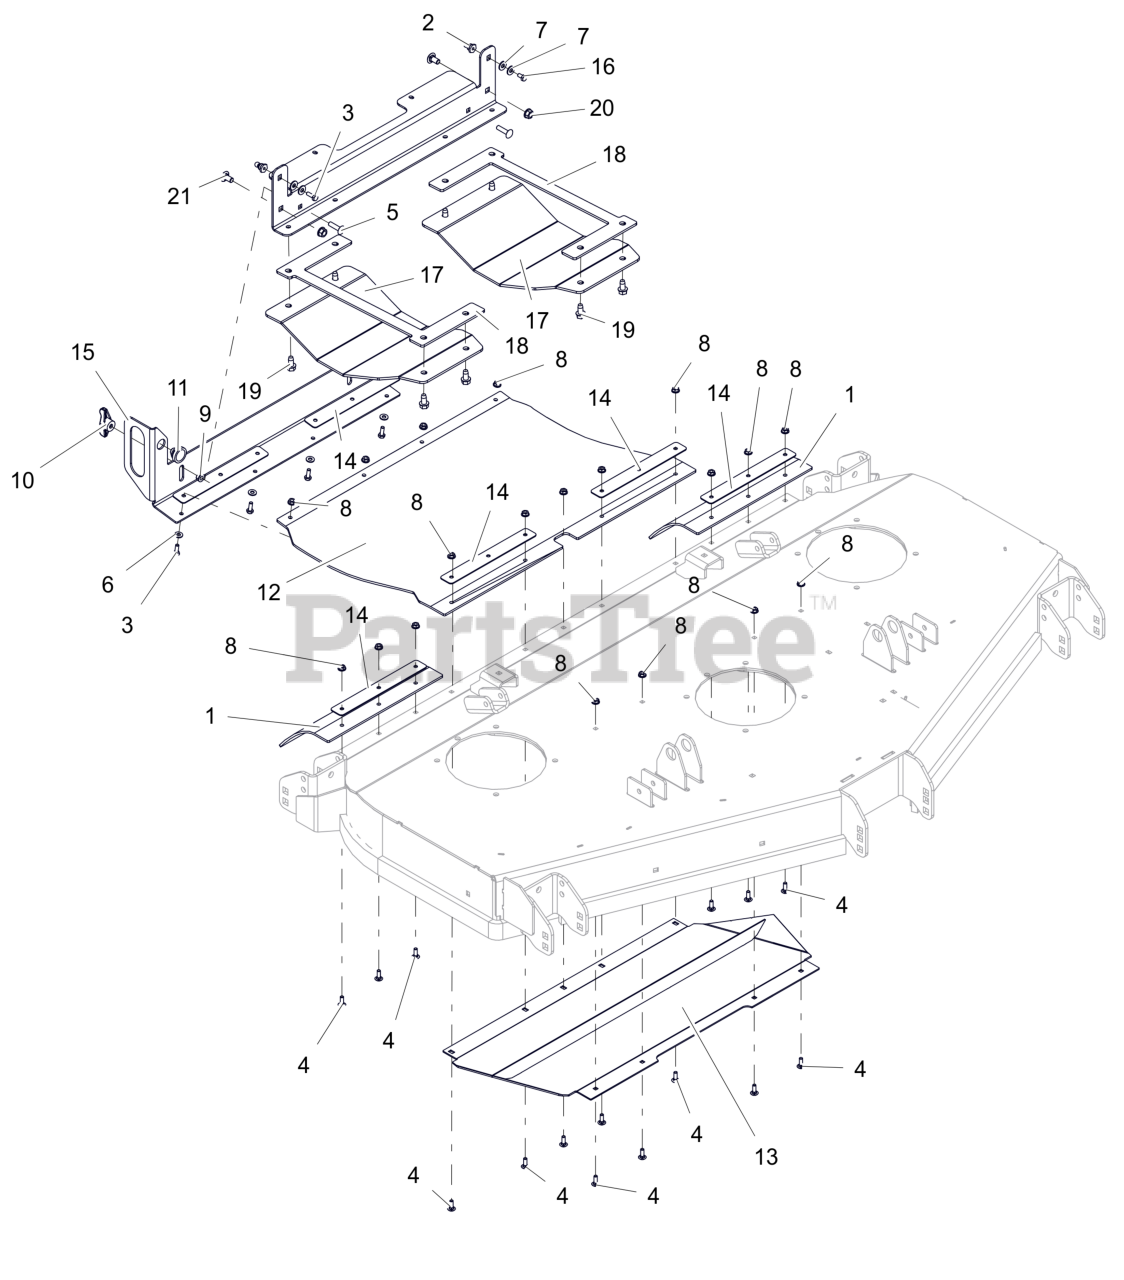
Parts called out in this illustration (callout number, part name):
1	FLAP, REAR DISCHARGE 60" TIRE
2	STUD, BALL FEMALE .250-20 THREAD
3	BLT, HEX .25-20X.75 G5 ZCC
4	BLT, RHSN .25-20X.750 G5 ZCC
5	BTL,RHSSN .313-18 X 1.25 G5 ZCC
6	WSHR,FLT .281X.625X.065 ZCC
7	WSHR, FLT .312X.734X.065 ZCC
8	NUT-LK-CTR-FLG .25-20 ZC120
9	NUT,LK-CTR-FLG .31-18 GF ZCC
10	KNOB,WING .31-18 UNC NYL/TALC
11	COUPLING, RUBBER PUSH-IN
12	CHUTE- 52" REAER DISCHARGE
13	WLDMT, DEFLECTOR BAFFLE (RED)
14	PLATE, CHUTE MTG (BLACK)
15	HANDLE, CHUTE MOUNTING (RED)
16	BLT,HEX .25-20X.50 G5 ZCC
17	PLATE, SKID (BLACK)
18	PLATE, SKID TENSION (BLACK)
19	SCR,TAP .375-16X.75 HWH TR ZCC
20	NUT-LK-CTR-FLG .375-16 GF ZCC
21	BLT, RHSSN .38-16X.75 G5 ZCC
